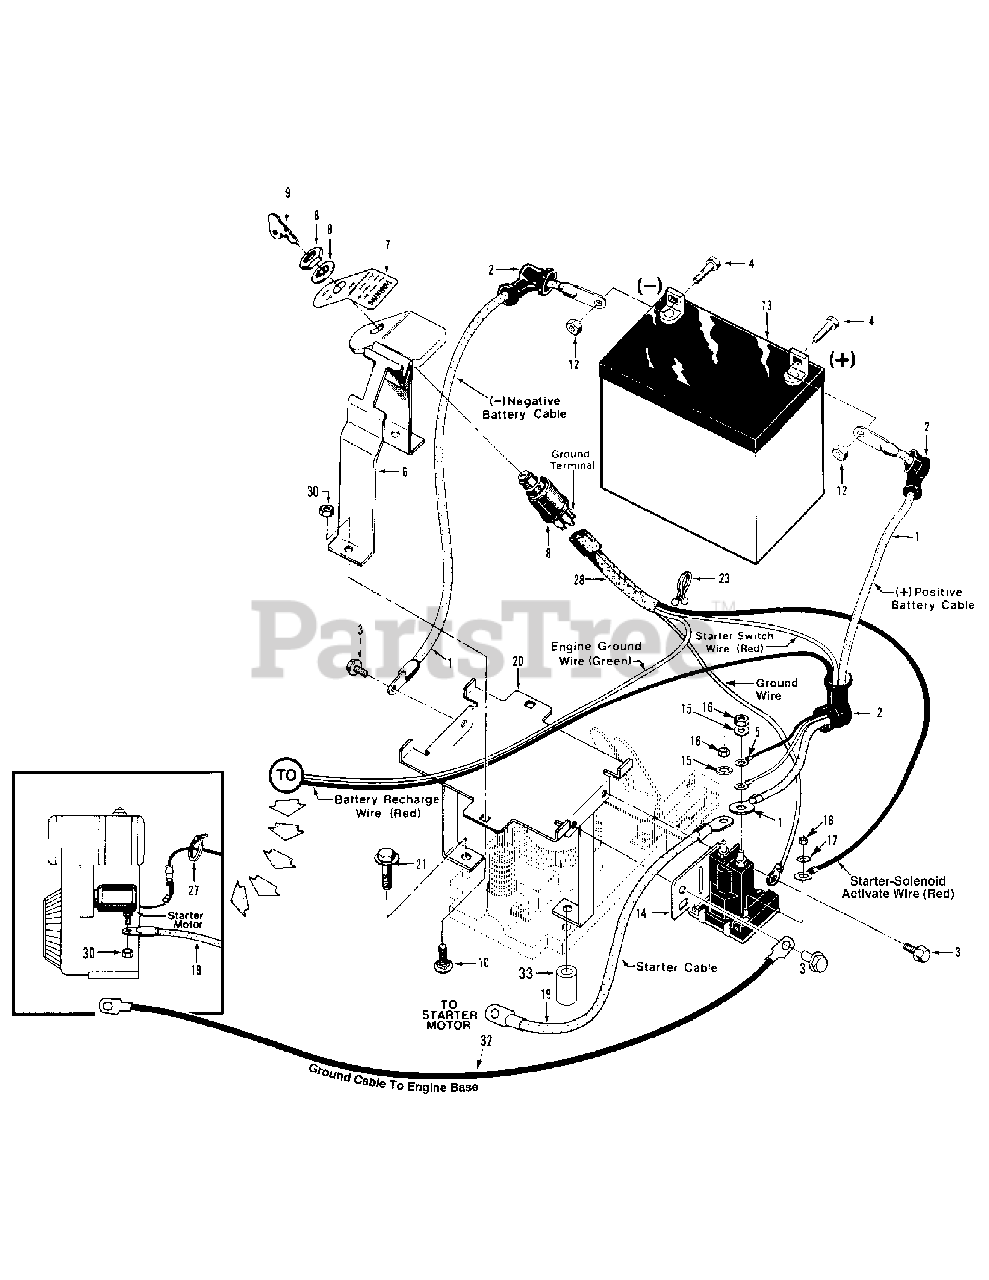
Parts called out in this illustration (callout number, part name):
1	Cable-battery, positive and negative terminals
2	Boot-terminal insulating
3	Screw-TT, 1/4-2 x 1/2"
4	Bolt-hex hd., 1/4-20 x 5/8"
5	Wire-recharge (red)
6	Battery Hold-down Clamp-with attached Key Switch Plate
7	Decal- ignition switch instruction
8	Key Switch-Includes two ignition keys (Ref. 9), one lockwasher, & one mounting nut
9	Key-ignition, one pair
10	Bolt-carriage, 1/4-20 x 1-1/4"
11	Lockwasher-spring lock, 1/4"
12	Nut-hex, 1/4"-20
13	Battery-12 volt, 270 CCA
14	Solenoid-starter, incl. Nuts & washers for cables & wires
15	Lockwasher-5/16"
16	Nut-hex, 5/16"-24
17	Lockwasher-external tooth, #10
18	Nut-hex. #10-32
19	Cable-solenoid to starter motor
20	Battery Bracket
21	HH Cap Screw, 3/8-16 x 2.75
23	Tie-plastic;, wire retaining
27	Tie-plastic
28	Wire Harness & Connecting Terminal Assembly
30	Locknut-hex, 1/4"-20
32	Cable-ground, solenoid to engine block
